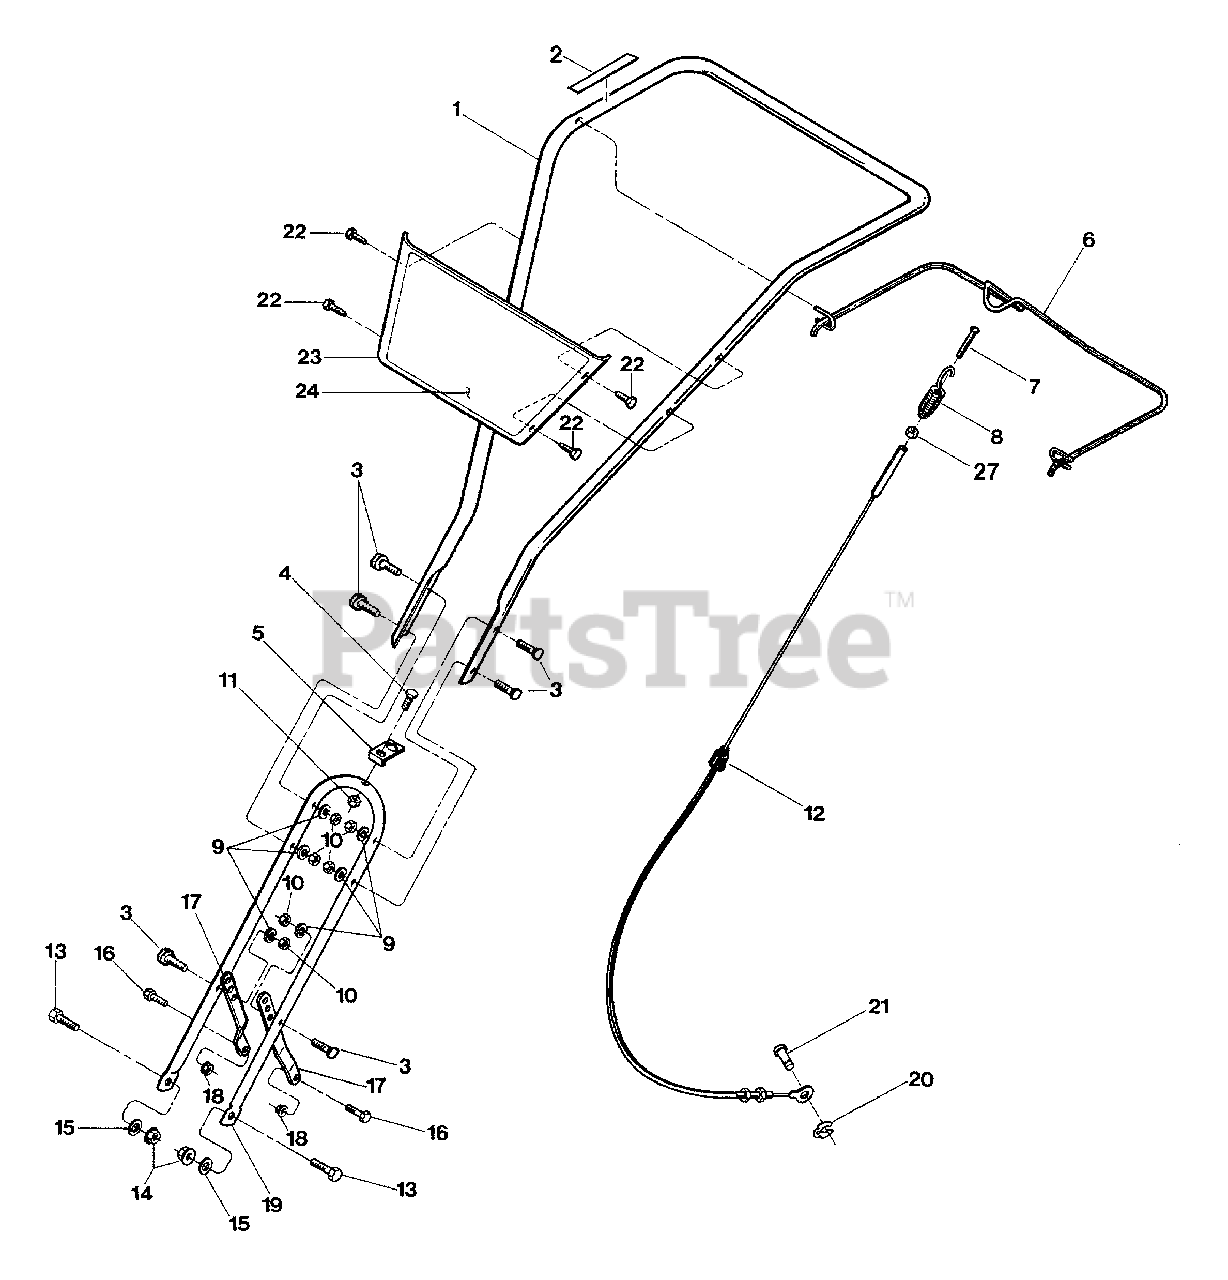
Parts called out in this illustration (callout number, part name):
1	Upper Handlebar
2	Decal, Forward Clutch Bail
3	Hex Hd. Screw, 5/16-18 x 1-1/2
4	Hex Screw, 1/4-20 x 1-1/4
5	Bracket, Forward Clutch Cable
6	Bail, Forward Clutch
7	Screw, #10-24 x 2
8	Spring, Forward Clutch
9	Lockwasher, 5/16
10	Hex Locknut, 5/16-18
11	Hex Locknut, 1/4-20
12	Cable Assy, Forward Clutch
13	Hex Screw, 3/8-16 x 3/4
14	Hex Locknut, 3/8-16
15	Flat Washer, 3/8
16	Hex Screw, 5/16-18 x 3/4
17	Handlebar Support
18	Hex Locknut, 5/16-18
19	Lower Handlebar
20	Klip Ring
21	Clevis Pin
22	Hex Screw, 1/4-20 x 1/2, Self-Tap
24	Decal, Model Name/Logo
27	Hex Nut, #10-24
